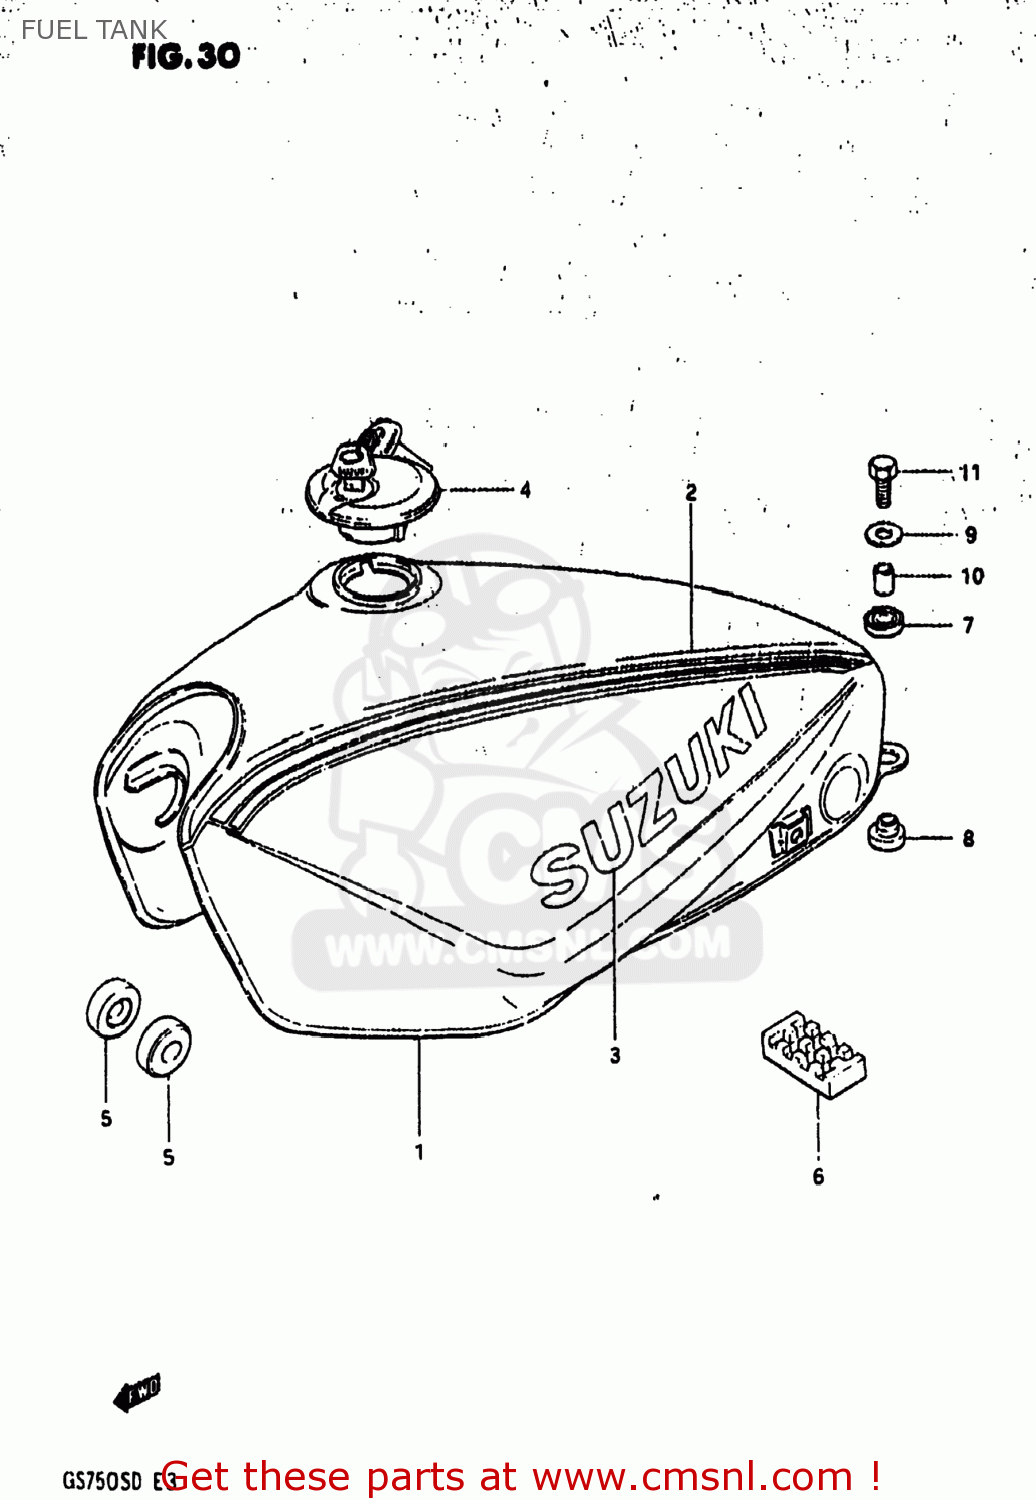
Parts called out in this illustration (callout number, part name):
1	TANK ASSEMBLY,FUEL
2	TAPE SET,FUEL TANK STRIPE
3	EMBLEM(ORANGE)
4	CAP SET,FUEL TANK
5	CUSHION
6	CUSHION,FUEL TANK CTR
7	CUSHION
8	CUSHION
9	WASHER (6.5X24X1.6)
10	SPACER
11	BOLT
